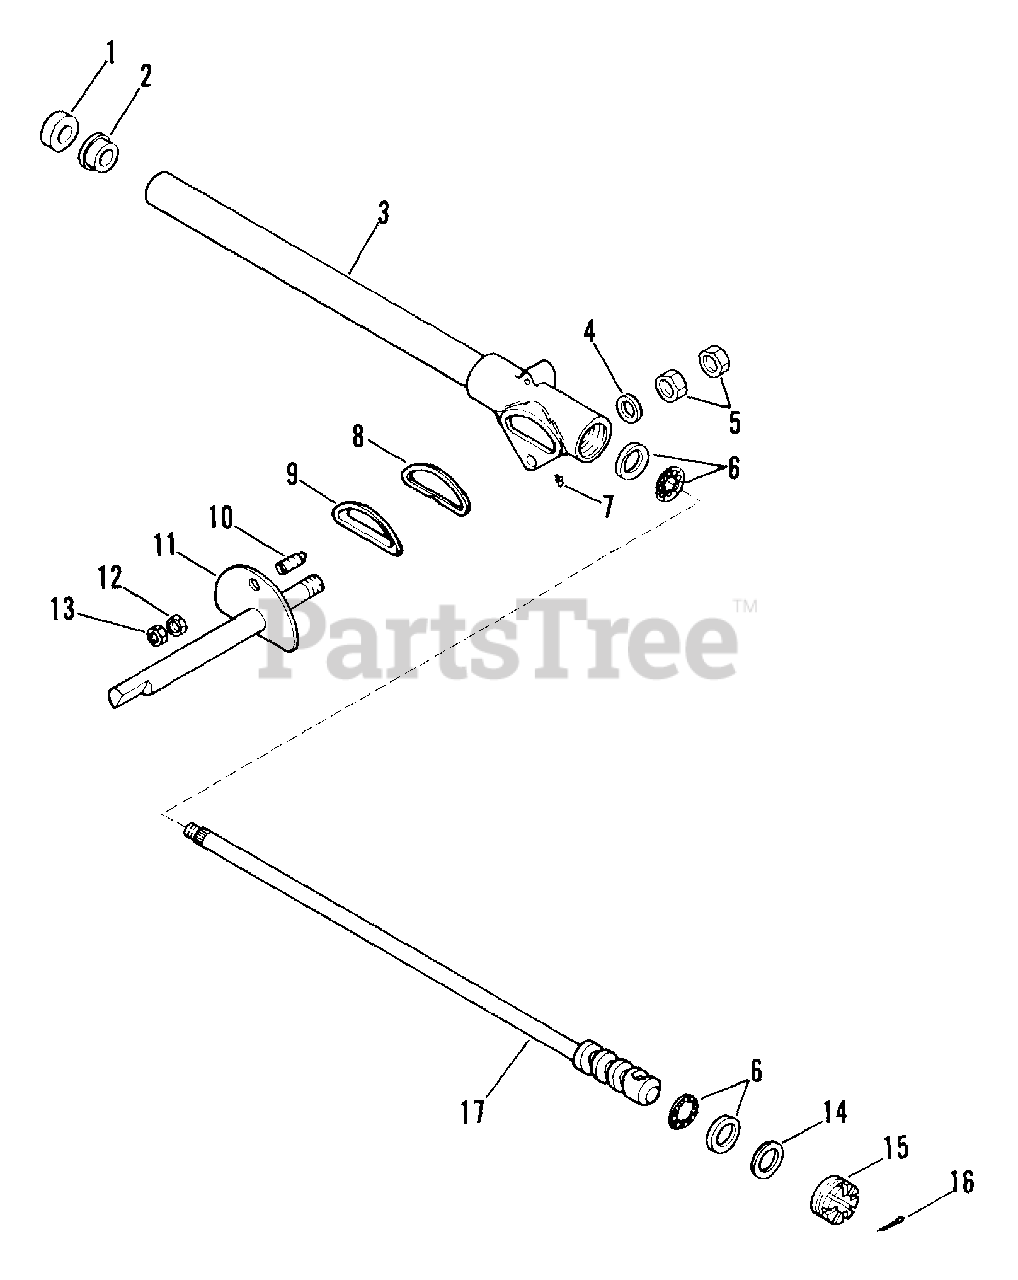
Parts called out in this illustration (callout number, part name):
1	DUST COVER
2	BSHG ROSS G#061013
3	HOUSING ASSEMBLY
4	WSHR-FL-STL .760X1.250X.060 PL
5	NUT-JAM .75-16 PL
6	BEARING KIT
7	HYDRAULIC DRIVE FITTING
9	RETAINER - SEAL
10	STUD LEVER
11	STEERING SHAFT
12	NUT .562-18
13	NUT- .562-18
14	WSHR-BLVL 1.015X1.470X.044
16	PIN-COTR .12X.50 PL
17	STEERING GEAR ASS'Y
